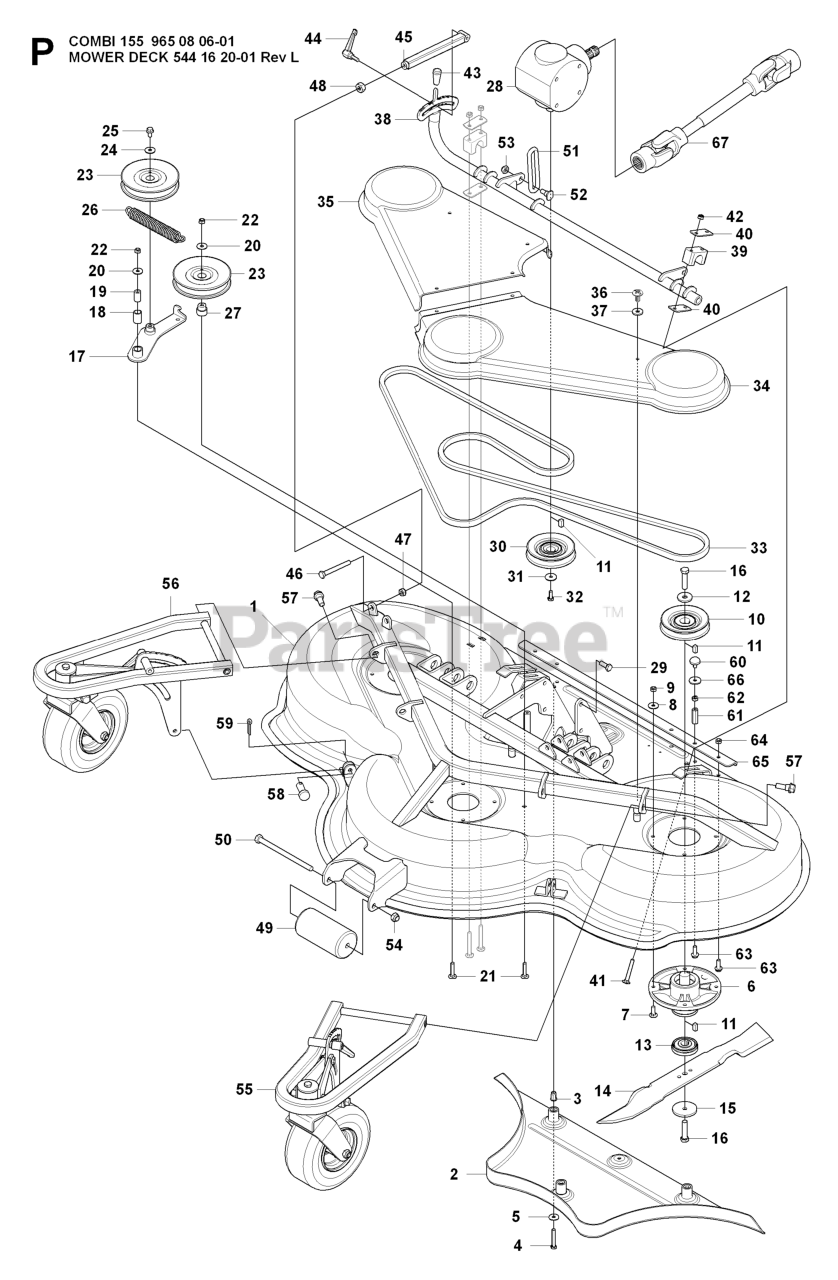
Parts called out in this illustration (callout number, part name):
2	PLUG ASSEMBLY
3	BLIND RIVET NUT
5	WASHER BRB 8.4X17
8	WASHER BRB 8.4X17
9	LOCKNUT M8
17	BELT TENSIONER CUTTING DECK
21	Screw Mvbf 8 X 40
22	LOCKNUT M8
25	BOLT FLANGE - M8X16
26	DRAW SPRING L=122
28	BEVEL GEAR
29	Screw M10x25
30	PULLEY SPB DP106
32	SCREW 8X20
34	BELT COVER C155 L
39	BEARING COVER
42	LOCKNUT M8
44	TURNING KNOB M 8
45	PARALLEL ROD NOT IN USE
48	NUT
49	ROLLER
52	SCREW LINK
53	NUT
55	WHEEL SUSPENSION LEFT
56	WHEEL SUSPENSION RIGHT
60	ANTIVIBRATION ELEMENT
62	NUT
64	LOCKNUT M8
65	REINFORCING PLATE DECK SHELL
